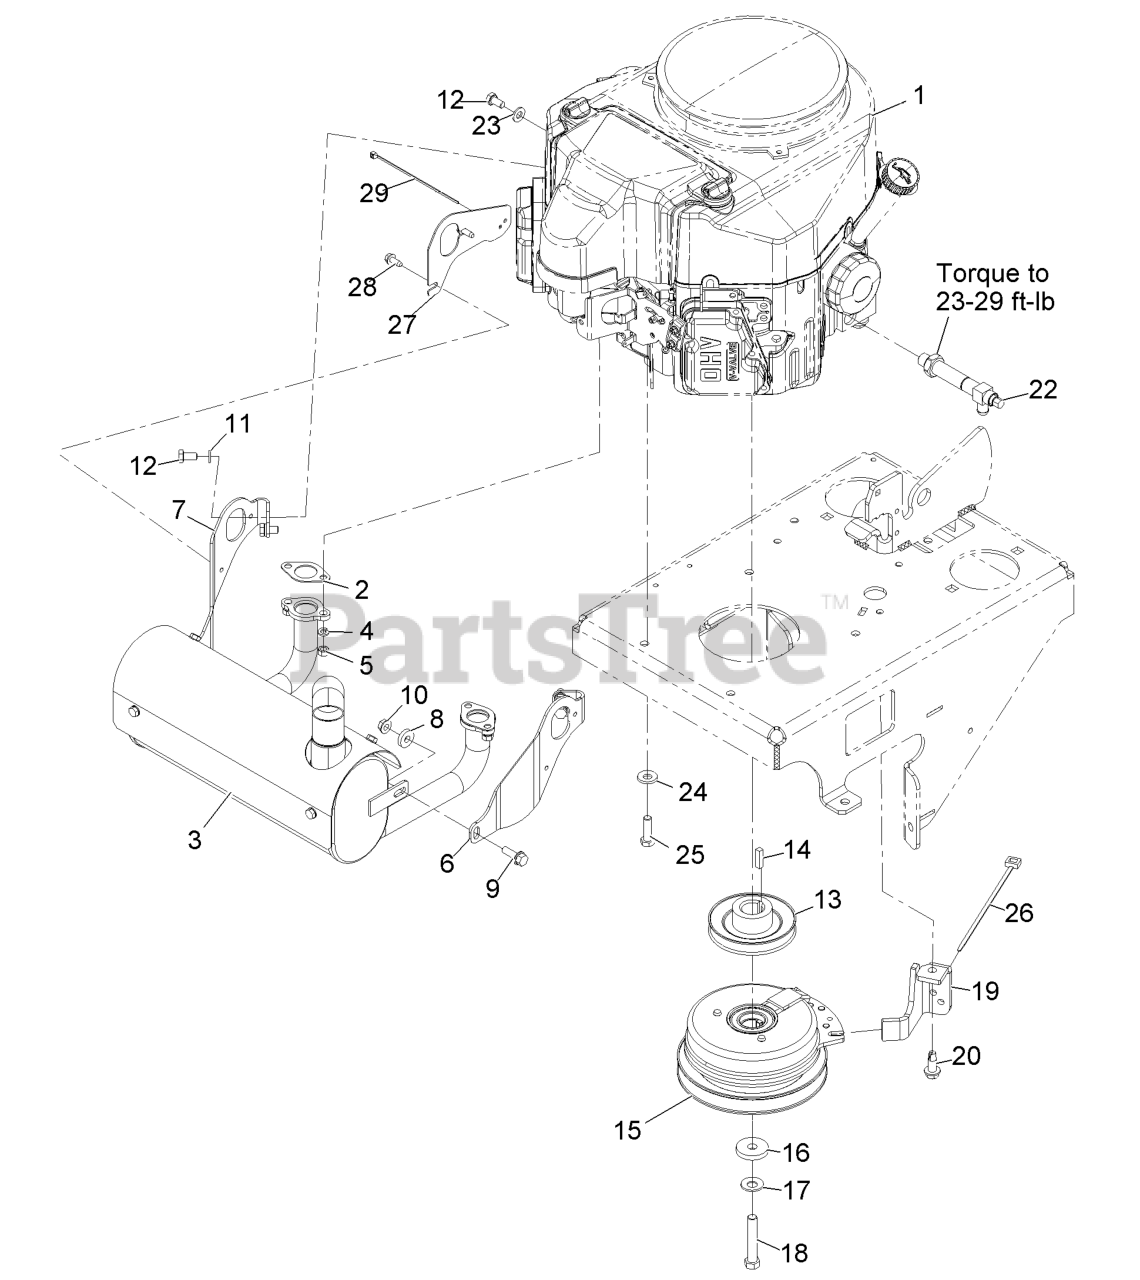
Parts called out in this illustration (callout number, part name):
2	GASKET-EXHAUST
4	WASHER-LOCK
6	BRACKET-MUFFLER MOUNT, LH
7	BRACKET-MUFFLER MOUNT, RH
9	SCREW-HHF
11	WASHER-LOCK
12	SCREW-HH
13	PULLEY
15	CLUTCH-175 FT-LB
16	WASHER
17	WASHER-SPRING
18	SCREW-HH
19	ANCHOR-CLUTCH
20	SCREW-TAPPING
23	WASHER-PLAIN
24	WASHER-BELLEVILLE
25	SCREW-HH
26	TIE-CABLE
27	GUARD-CABLE, SPARK PLUG
28	SCREW-HWH
29	TIE-CABLE
